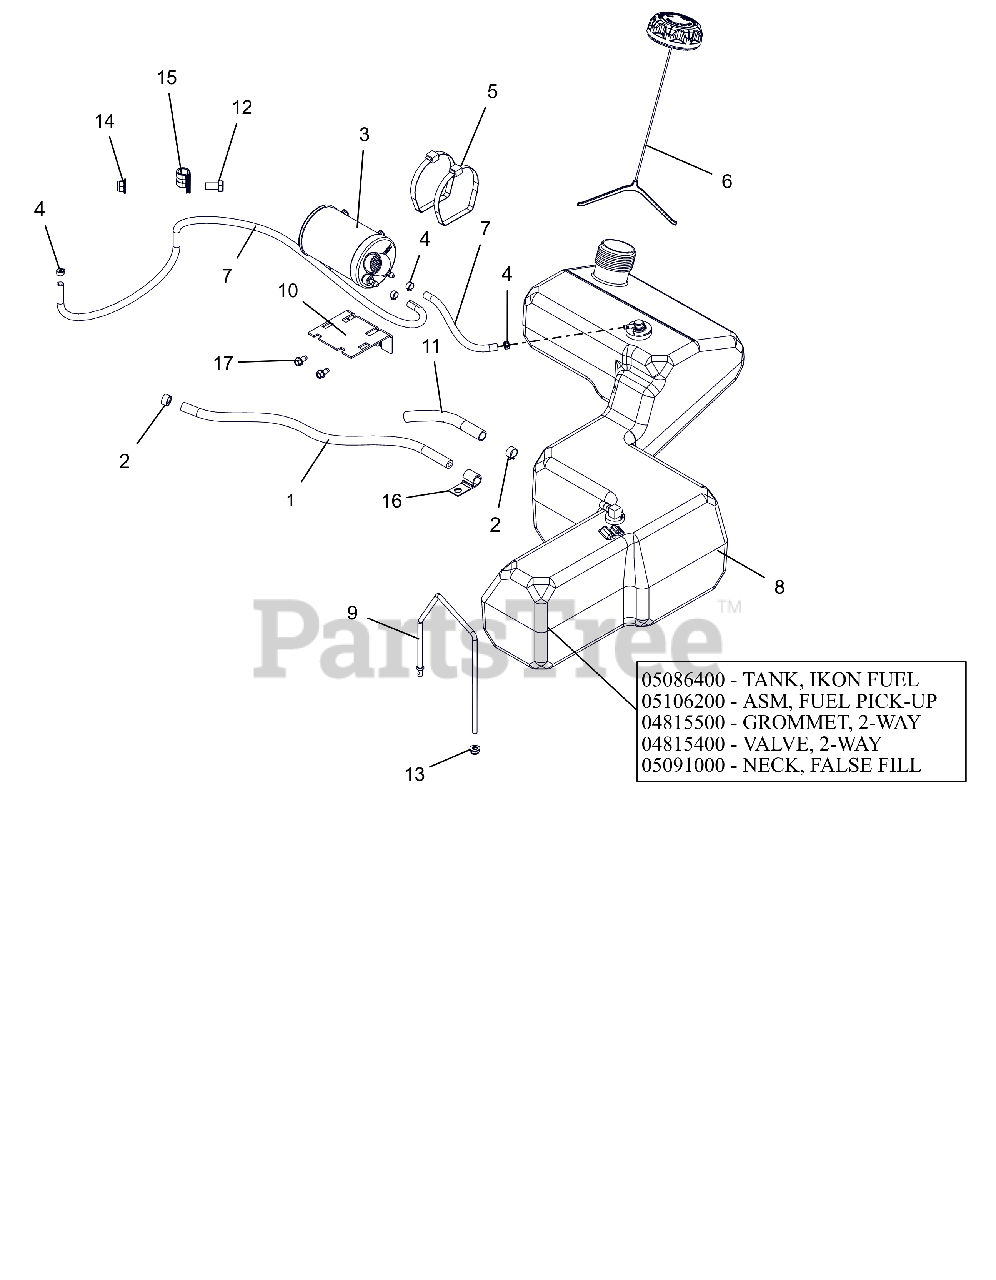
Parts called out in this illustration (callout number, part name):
1	HOSE, .25 LOW-PERM BULK GAS
2	CLAMP, FUEL LINE
3	CARBON CANISTER, 300CC
4	CLAMP-HOSE, SPRING .188
5	P-PLASTIC TIE STRAP LARGE
6	CAP, FUEL VENT-IN 2.25" RATCH.
7	HOSE, .188 30R7 BULK
8	ASSEMBLY, FUEL TANK IKON(2017)
8	TANK, IKON FUEL (2017)
8	ASM, IKON FUEL PICK-UP
8	GROMMET, 2-WAY
8	VALVE, 2-WAY
8	NECK, FALSE FILL-2017 IKON
9	BRKT, FUEL TANK HOLD DOWN
10	BRKT, MOUNT -CARB CANISTER
11	WRAP, ANTIABRASION .5X.064WALL
12	@BLT-HEX .38-16X.75 GR5 YWZC
13	@NUT-LK-NYL-FLG .25-20 YWZC
14	@NUT-LK-NYL-FLG .38-16 YWZC
15	CLAMP, CUSHIONED STEEL
16	J-CLAMP
17	SCR-TAP .25-20X.50 HWH TR YWZ
